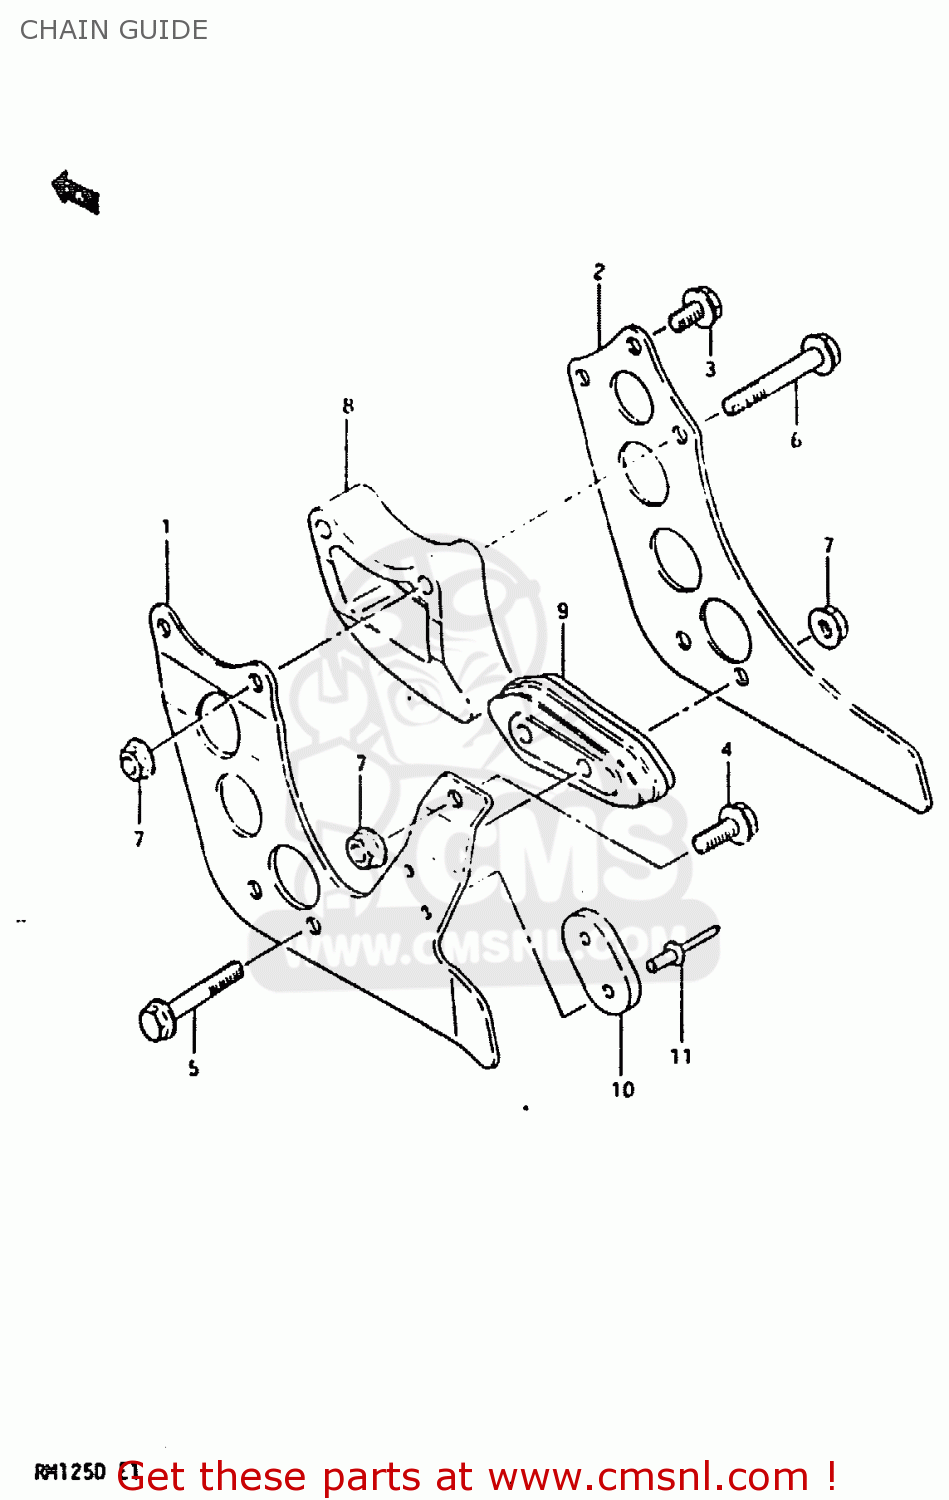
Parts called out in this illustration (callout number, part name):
1	PLATE,CHAIN GUIDE,OUTER
2	PLATE,GUIDE CHAIN
3	BOLT
4	BOLT
5	BOLT
6	BOLT,UNDER
7	NUT
8	DEFENSE,CHAIN GUIDE UPR
9	DEFENSE,CHAIN GUIDE
10	PAD,DRIVE CHAIN GUIDE
11	RIVET
